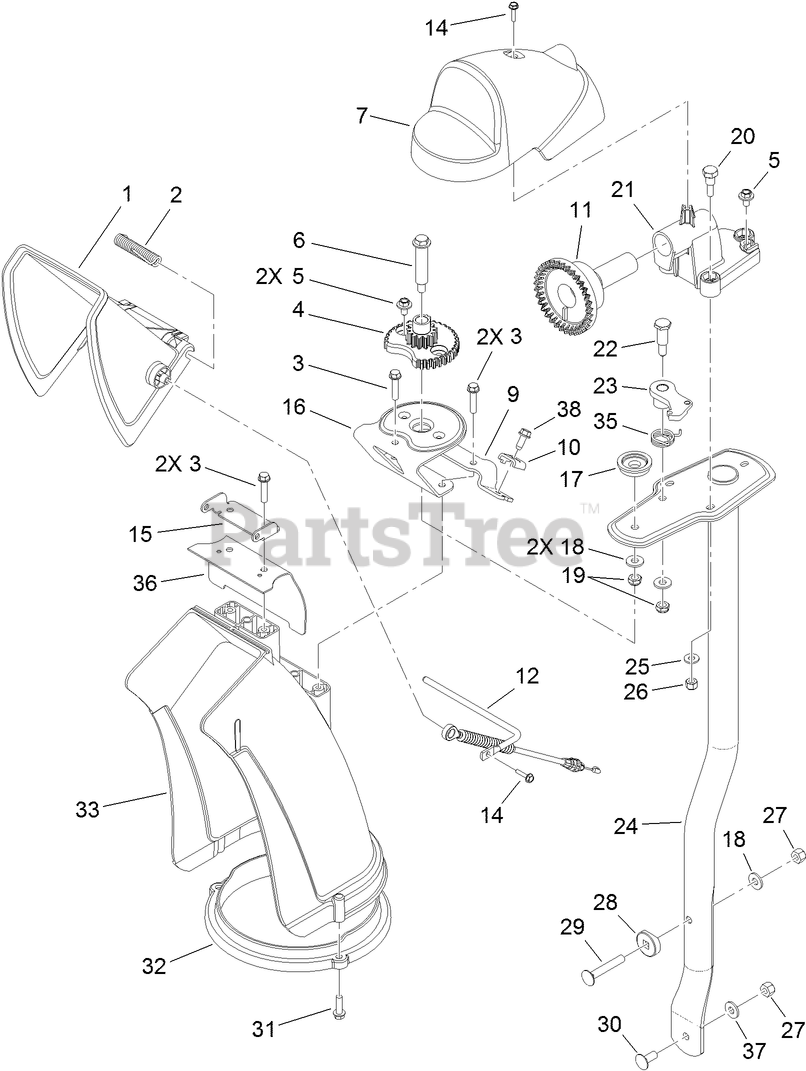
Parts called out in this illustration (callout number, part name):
1	DEFLECTOR-CHUTE, CE
2	SPRING-TORSION
3	SCREW-PLASTITE
4	GEAR-CHUTE
5	SCREW AND WASHER ASM
6	BOLT-SHOULDER
7	COVER-GEAR, CHUTE
9	BRACKET-CABLE, CLAMP
10	CLAMP-CABLE
11	GEAR-FACE
12	ROD-DEFLECTOR
14	SCREW-HWH
15	BRACKET-DEFLECTOR
16	BRACKET-SUPPORT, CHUTE
17	SPACER-CHUTE
18	WASHER-FLAT
19	NUT-LOCK, NI
20	SCREW-SHOULDER
21	MOUNT-GEAR, FACE
22	SCREW-SHOULDER
23	LATCH-CHUTE
24	TUBE-SUPPORT
25	WASHER-FLAT
26	NUT-LOCK, NI
27	NUT-LOCK, NI
28	WASHER-CURVED
29	BOLT-CAR
30	SCREW-CARR
31	SCREW-HWH
32	RING-CHUTE
33	CHUTE-DISCHARGE
35	SPRING-TORSION
36	SEAL-CHUTE
37	WASHER-BELLEVILLE
38	SCREW-HWH
